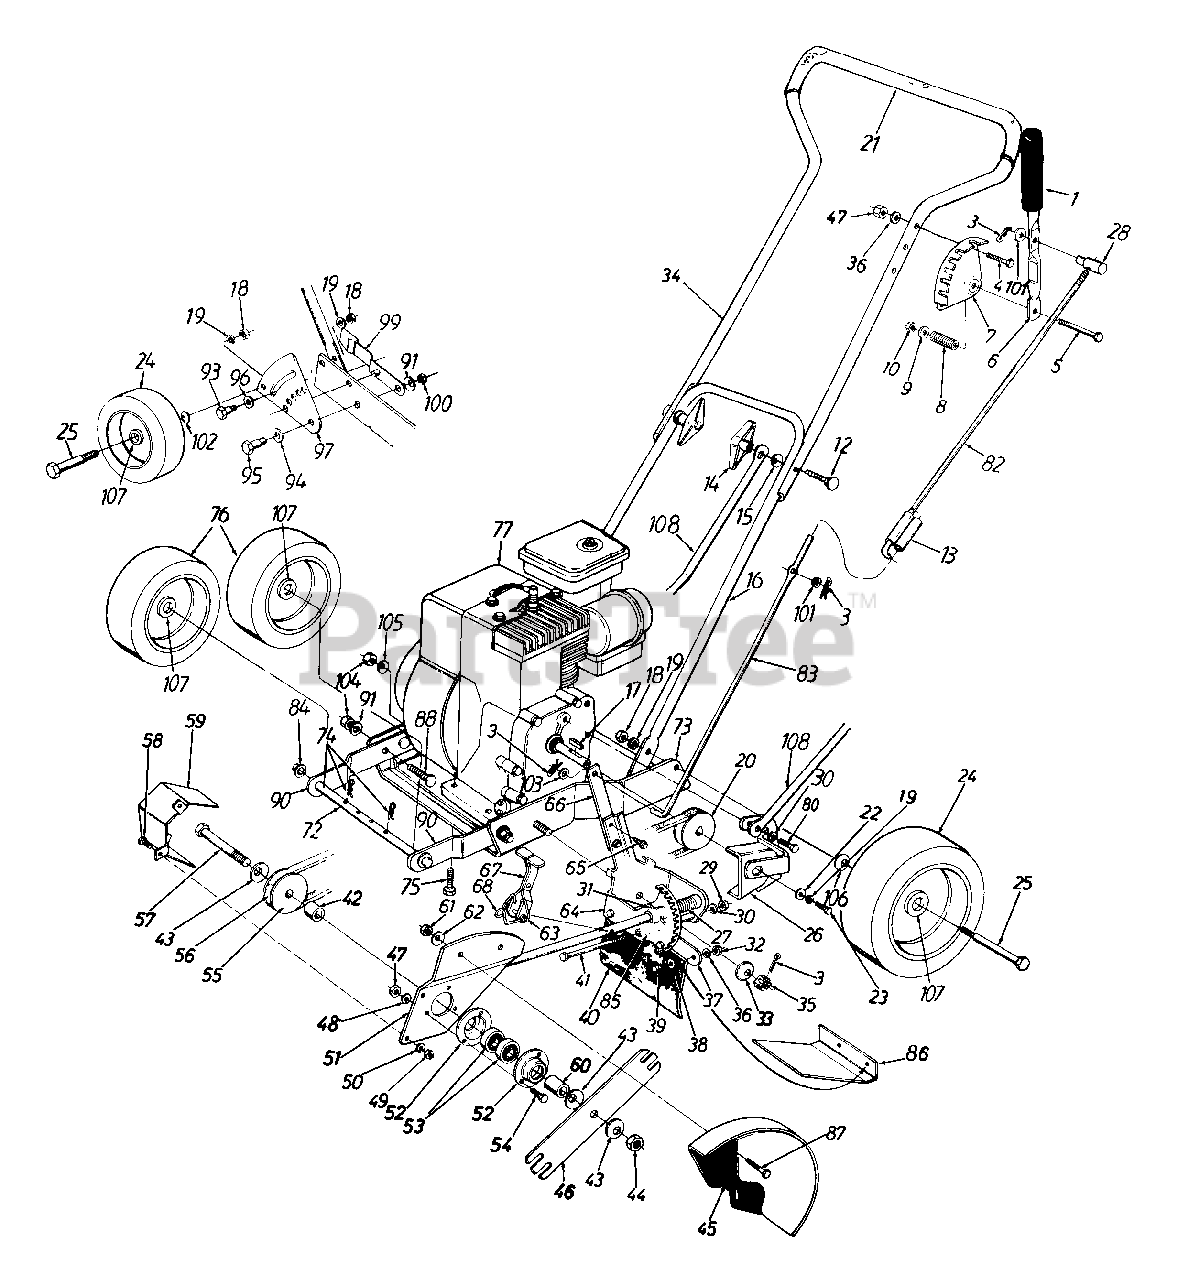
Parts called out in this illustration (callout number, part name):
1	Foam Grip
3	Cotter Pin 5/16" Dia.
4	Hex Bolt 1/4-20 x 1.25" Lg.
5	Hex Bolt 5/16-18 x 2" Lg.
8	Compression Spring 1.38" Lg.
9	FI-Wash .344" I.D.
10	Hex L-Nut 5/16-18 Thd.
12	Curv. Hd. Bolt 5/16-18 x 2" Lg.
13	Clutch Rod Lock
14	Wing Nut Ass'y.
15	Saddle Wash .32" I.D. x .937"
18	Hex Nut 3/8-16 Thd.
19	L-Wash. 3/8" I.D.
20	Engine Pulley
21	Foam Grip
22	FI-Wash .385" I.D.
23	Hex Bolt 3/8-24 x 1" Lg.
24	Rear Wheel Ass'y.
25	Shoulder Bolt .498" Dia.
28	Ferrule
29	Hex Nut 5/16-18 Thd.
30	L-Wash. 5/16" I.D.
31	Spring Pin Spir. 1/4" Dia.
32	Hex Nut 1/4-20 Thd.
33	Bell-Wash .535" I.D.
34	Upper Loop Handle
35	Hex Slotted Nut 1/2-20 Thd.
36	L-Wash. 1/4" I.D.
37	Flap Bracket
38	FI-Wash .25" I.D.
39	Hex Bolt 1/4-20 x .62" Lg.
41	Hex Bolt 5/16-18 x 4.5" Lg.
42	Spacer 1.030" Lg.
43	Bell-Washer .63" I.D.
44	Hex Jam L-Nut 5/8-18 Thd.
47	Hex Nut 1/4-20 Thd.
48	L-Wash. 1/4" I.D.
49	Hex Nut 1/4-20 Thd.
50	L-Wash. 1/4" I.D.
53	Ball Bearing .62" I.D.
54	Hex Bolt 1/4-20 x .62" Lg.
55	3/8" "V"-Pulley
56	"V"-Belt
57	Hex Bolt 5/8-18 x 4.5" Lg.
58	Hex Bolt 1/4-20 x .625" Lg.
60	Sleeve .90" Lg.
61	Hex Nut 5/16-18 Thd.
62	Bell-Wash .345" I D.
68	Torsion Spring
72	Axle 8.20" Lg. (Front)
75	Hex TT-Tap Scr. 3/8-16 x 1" Lg.
76	Front Wheel Ass'y
77	Engine
80	Hex Bolt 5/16-24 x .62" Lg
82	Upper Clutch Rod
83	Lower Clutch Rod
84	Push Cap 1/2" Dia.
85	Spacer 3 765" Lg.
88	Ribbed Neck Bolt 3/8-24 x .8" Lg.
93	Shld. Bolt .5" Dia.
94	Bell-Wash .515" I.D.
95	Shld. Bolt .50" Dia.
96	FI-Wash. .51" I.D. x.94"
100	Hex Jam Nut 3/8-16 Thd.
101	FI-Wash .344" I.D. x .62" O.D.
102	Wave Wash .51" I.D.
103	FI-Wash .406" I.D. x .81" O.D.
104	Hex Nut 3/8-24 Thd.
105	Bell-Wash .396" I.D. x 1 14" O.D.
107	Ball Bearing
